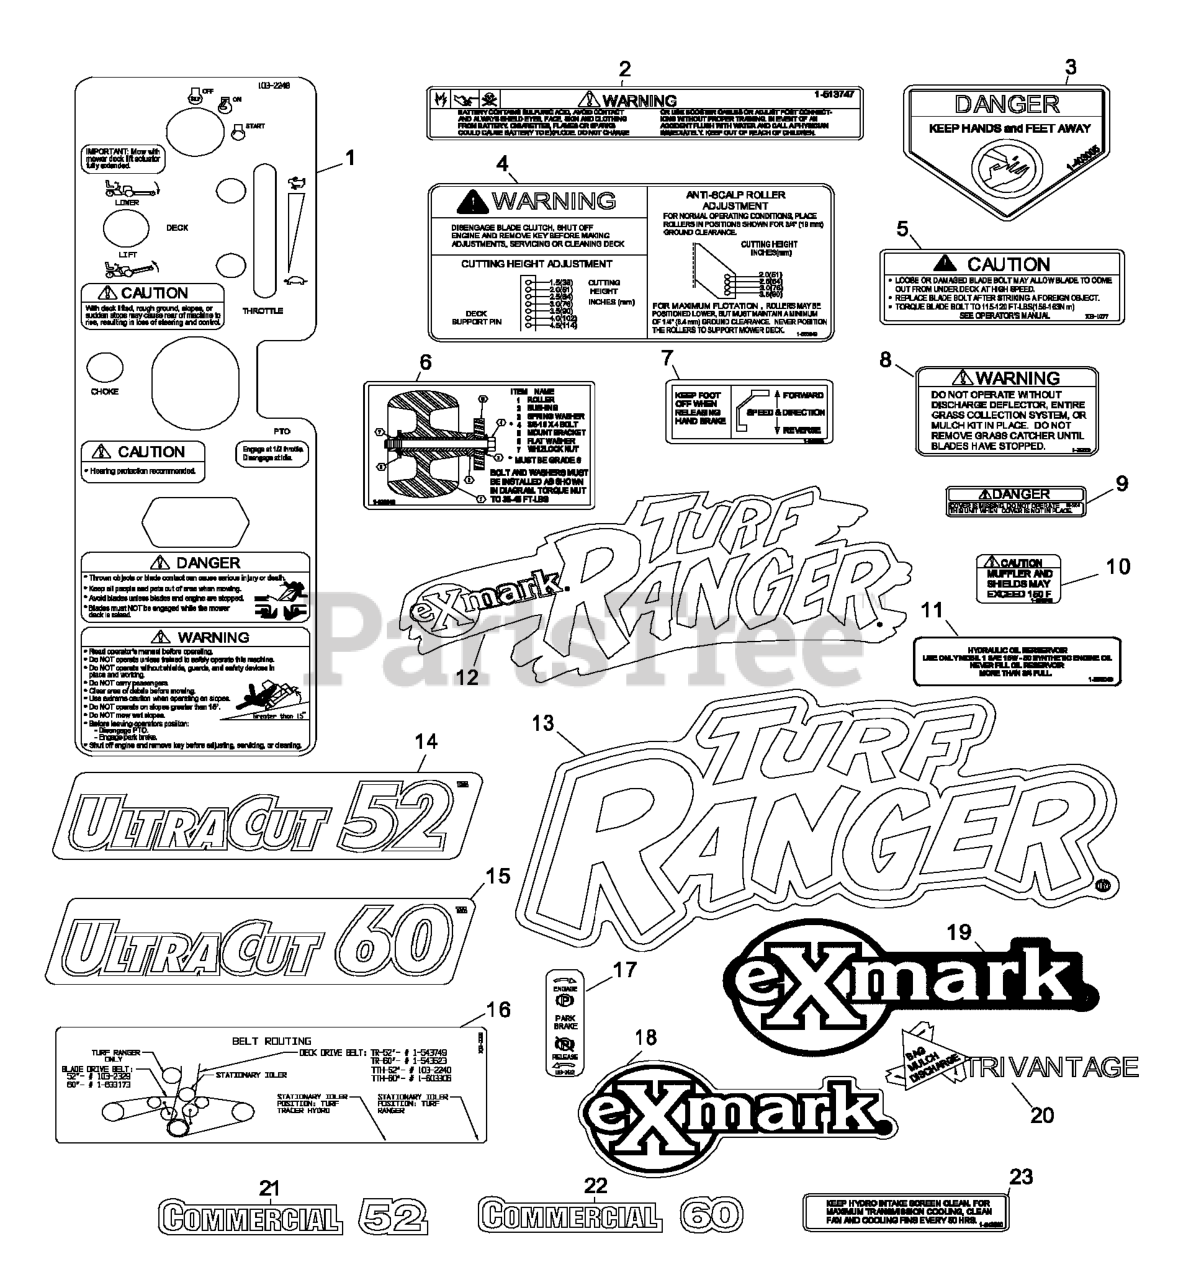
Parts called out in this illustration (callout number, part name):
1	DECAL, CONSOLE
2	DECAL-BATTERY
3	DECAL-DANGER
4	DECAL,ANTI SCALP
5	DECAL,BOLT TORQUE
6	DECAL,ROLLER MOUNTING
7	DECAL,FOOT PEDAL
8	DECAL-WARNING, DISCHARGE
9	DECAL-COVER, MISSING
11	DECAL,HYDRAULIC TANK
12	DECAL,SWASH RANGER
14	DECAL,ULTRACUT 52
15	DECAL,ULTRACUT 60
16	DECAL,BELT ROUTING
17	DECAL,PARKING BRAKE
18	DECAL,EXMARK LOGO
19	DECAL,EXMARK LOGO
21	DECAL,COMMERCIAL 52
22	DECAL,COMMERCIAL 60
23	DECAL,INTAKE
